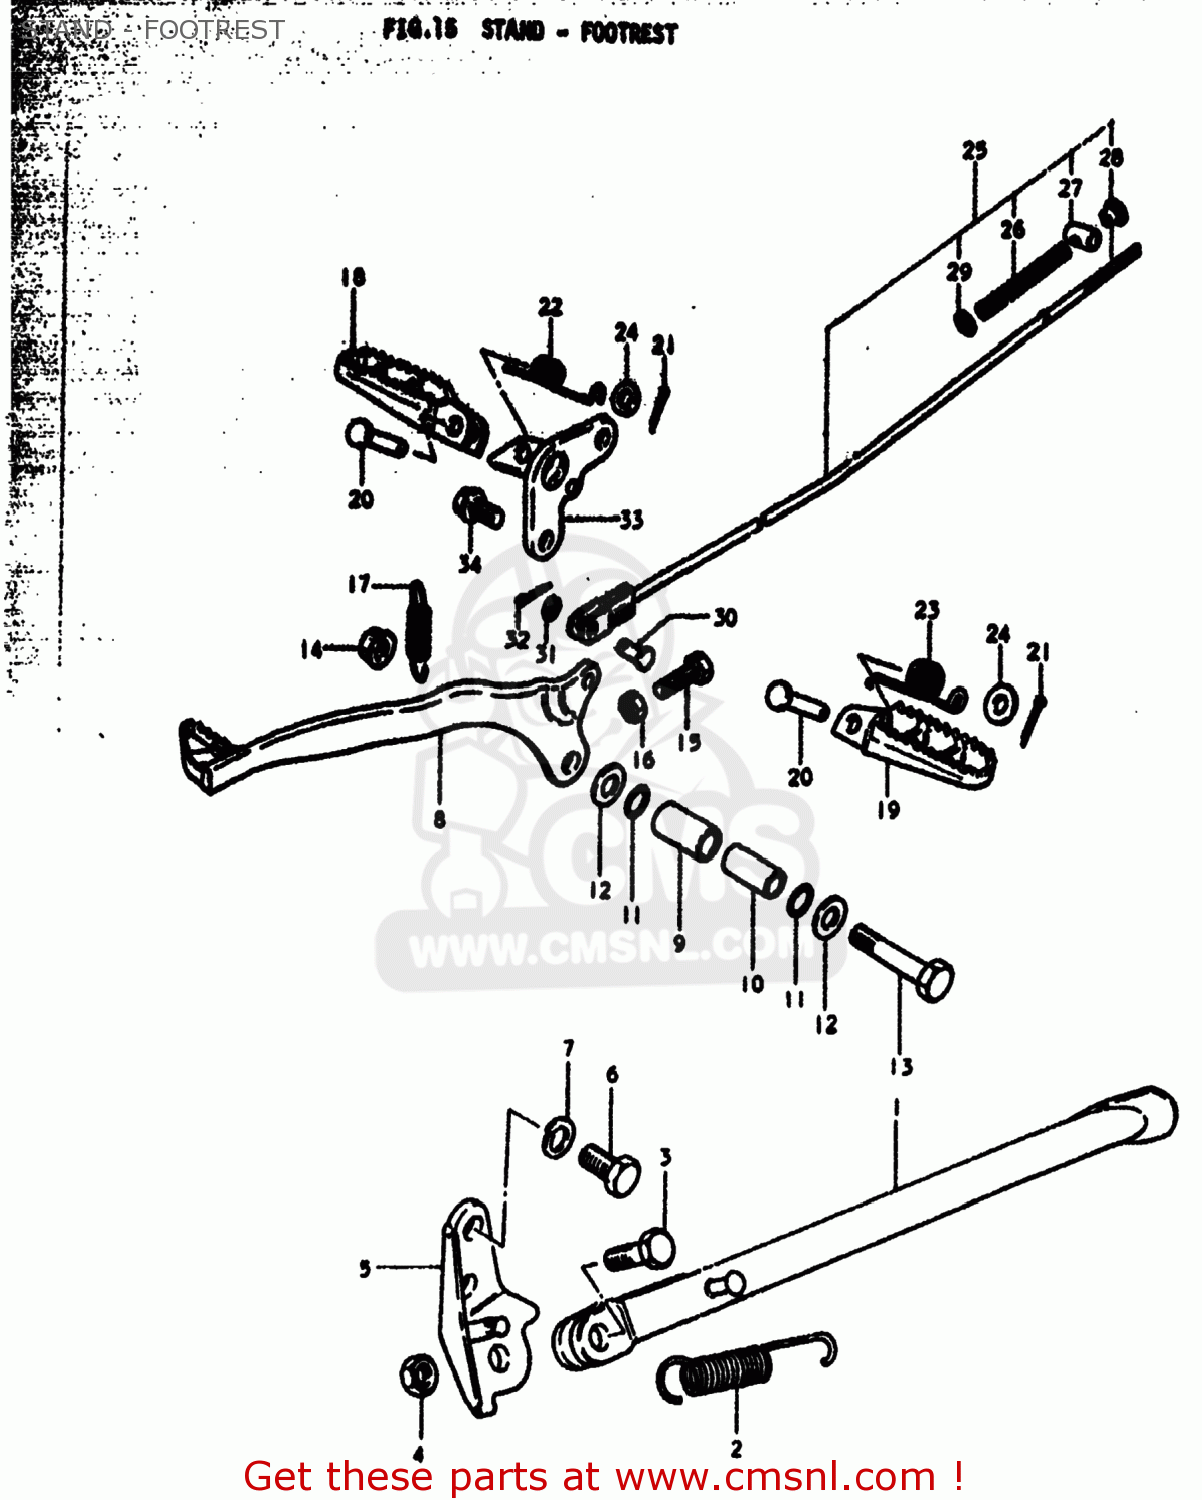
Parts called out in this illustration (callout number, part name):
1	STAND,SIDE
2	SPRING
3	BOLT(10X30)
4	NUT
5	BRACKET,PROP STAND
6	BOLT(10X19)
7	LOCK WASHER
8	PEDAL,BRAKE
9	BUSH
10	SPACER(10X14X32.2)
11	O RING(D:1.5,ID:13.8)
12	WASHER
13	BOLT
14	NUT
15	BOLT(6X23)
16	NUT
17	SPRING
18	RUBBER,FOOTREST
19	FOOTREST
20	PIN
21	PIN 20X20
22	SPRING
23	SPRING
24	WASHER
25	ROD ASSEMBLY,REAR BRAKE
26	SPRING
27	PIN
28	NUT
29	WASHER
30	PIN(L:13.5)
31	WASHER
32	PIN 20X20
33	HOLDER,FRONT FOOTREST,RIGHT
34	BOLT(10X20)
